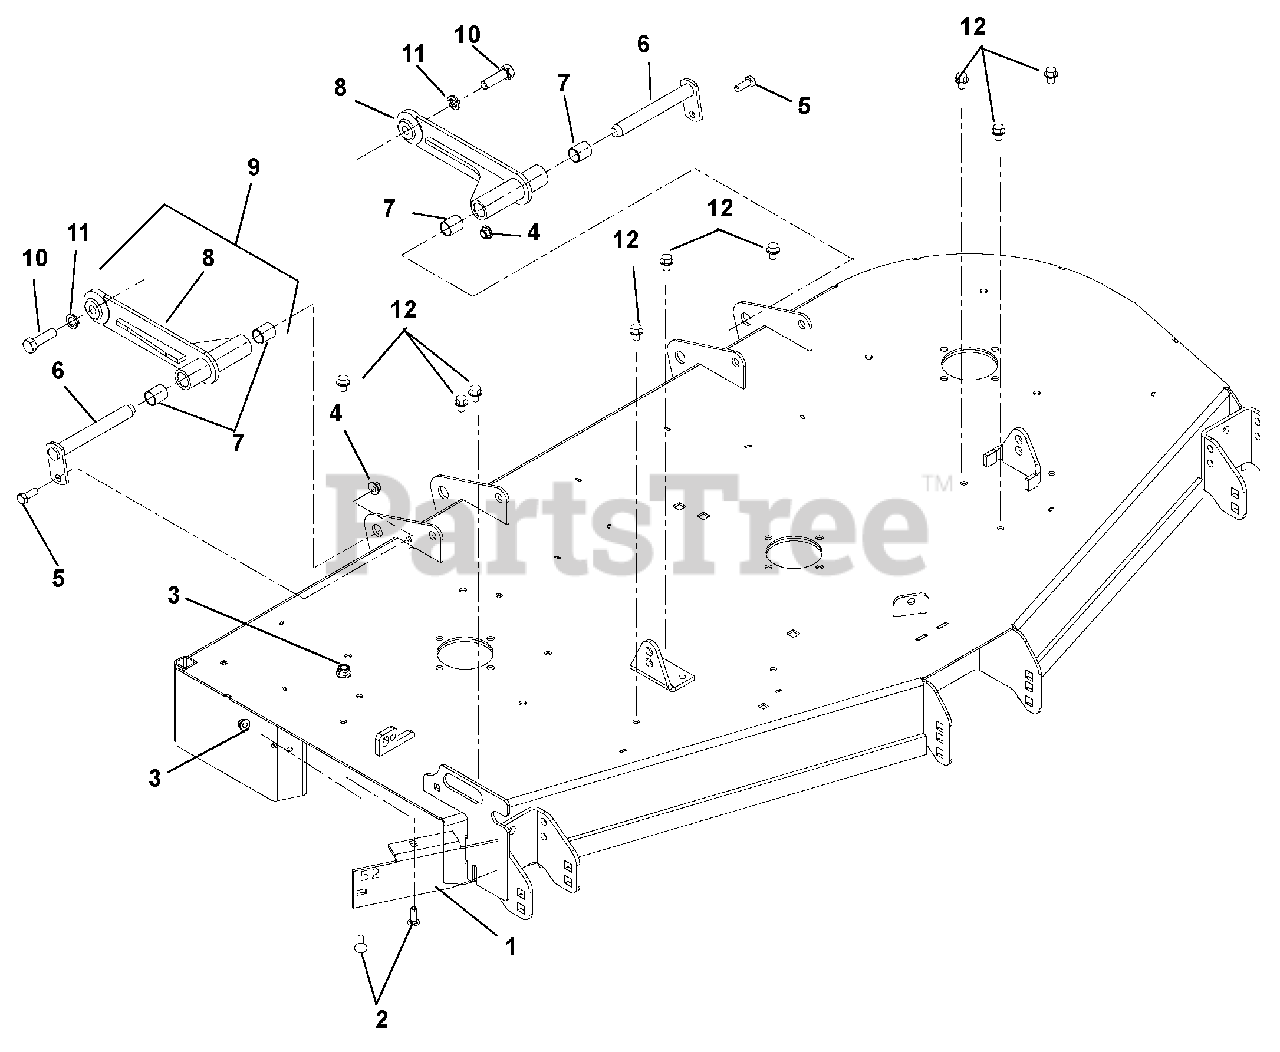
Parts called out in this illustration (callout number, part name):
1	BAFFLE, DISCHARGE 44/48
2	@BLT-RDHDSQNK .31-18X1.00 G5YZ
3	@NUT-LK-NYL-FLG .31-18 YWZC
4	@NUT-LK-NYL-FLG .38-16 YWZC
5	@BLT-HEX .38-16X1.00 GR5 YWZC
6	WELDMENT, MOWER MTG. PIN
7	BRG, .750 X .875 X 1.000
8	DECK PUSHER ARM WMT - BLACK
9	DECK PUSHER ARM ASSEMBLY
10	BLT-HEX .50-13X1.75 GR5EP80 YZ
11	@WSHR-LK .50X.125 REG YWZC
12	@SCR-TAP .38-16X.50 HWH TR YWZ
